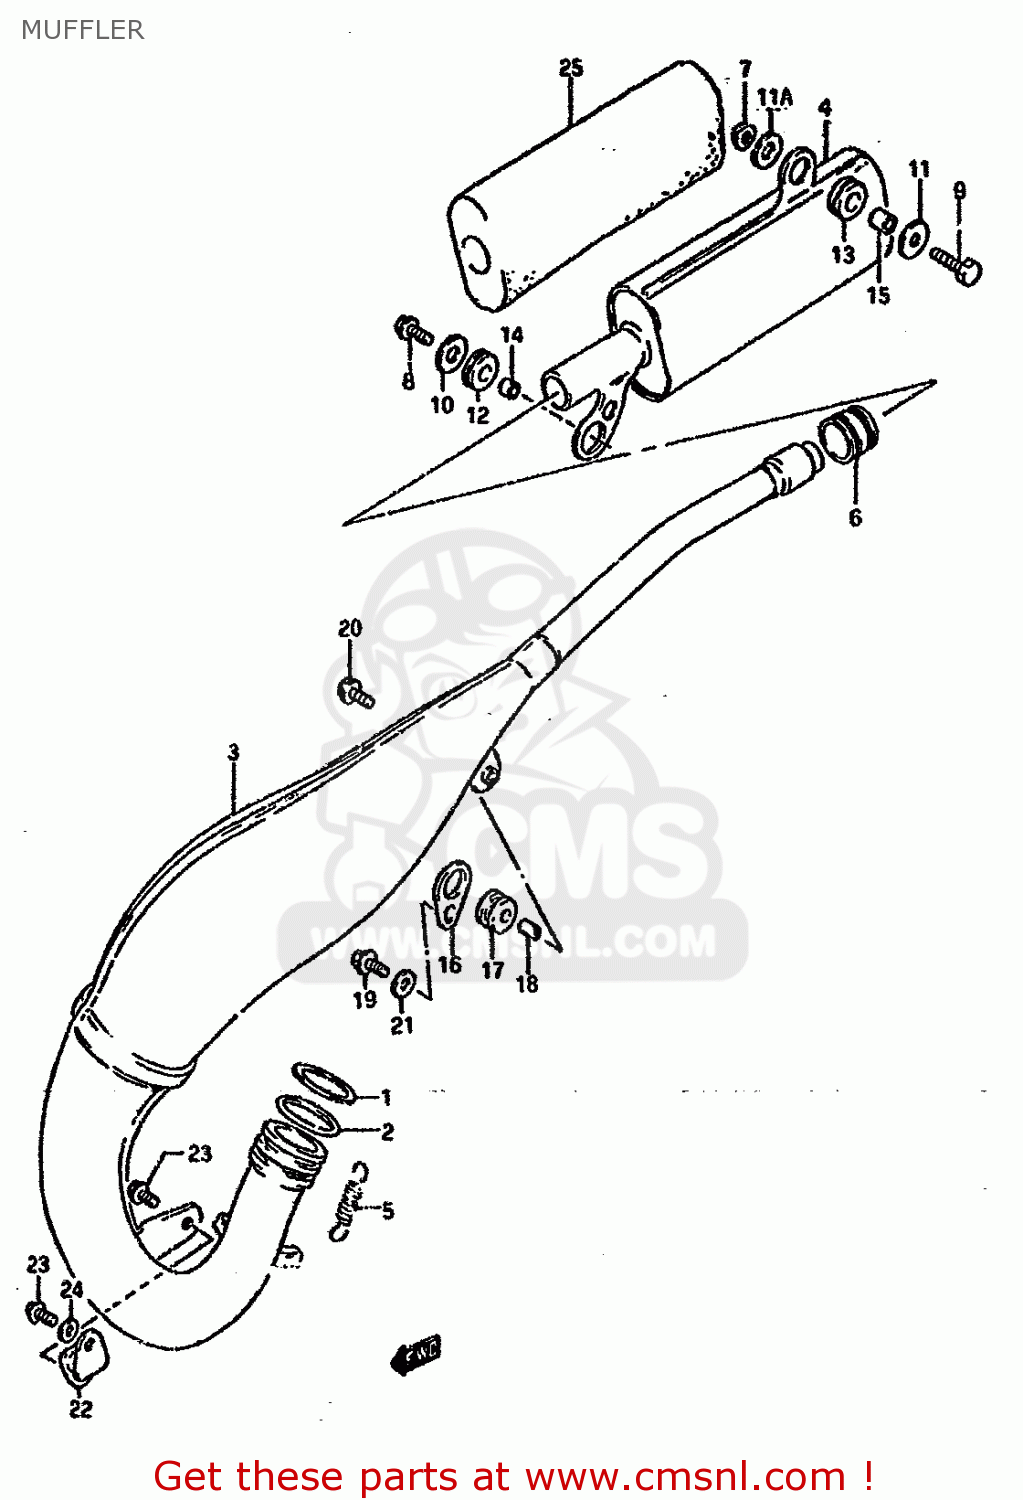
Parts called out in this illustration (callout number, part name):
1	WASHER,EXHAUST PIPE
2	O RING,EXHAUST PIPE
3	BODY,MUFFLER,FIRST
4	BODY,MUFFLER,SECOND
5	SPRING
6	CONNECTOR,MUFFLER
7	NUT
8	BOLT
9	BOLT
10	WASHER (6.5X24X1.2)
11	WASHER(8.5X26X1.2)
11A	WASHER (6.5X24X1.2)
12	CUSHION
13	CUSHION
14	SPACER (6.8X10X9)
15	SPACER(6.5X11.5X13)
16	PLATE,MUFFLER MTG
17	CUSHION,MUFFLER
18	SPACER (6.4X9X13.5)
19	BOLT
20	BOLT
21	WASHER
22	DAMPER,MUFFLER SUPPORT
23	BOLT
24	WASHER
25	SILENCER,MUFFLER
